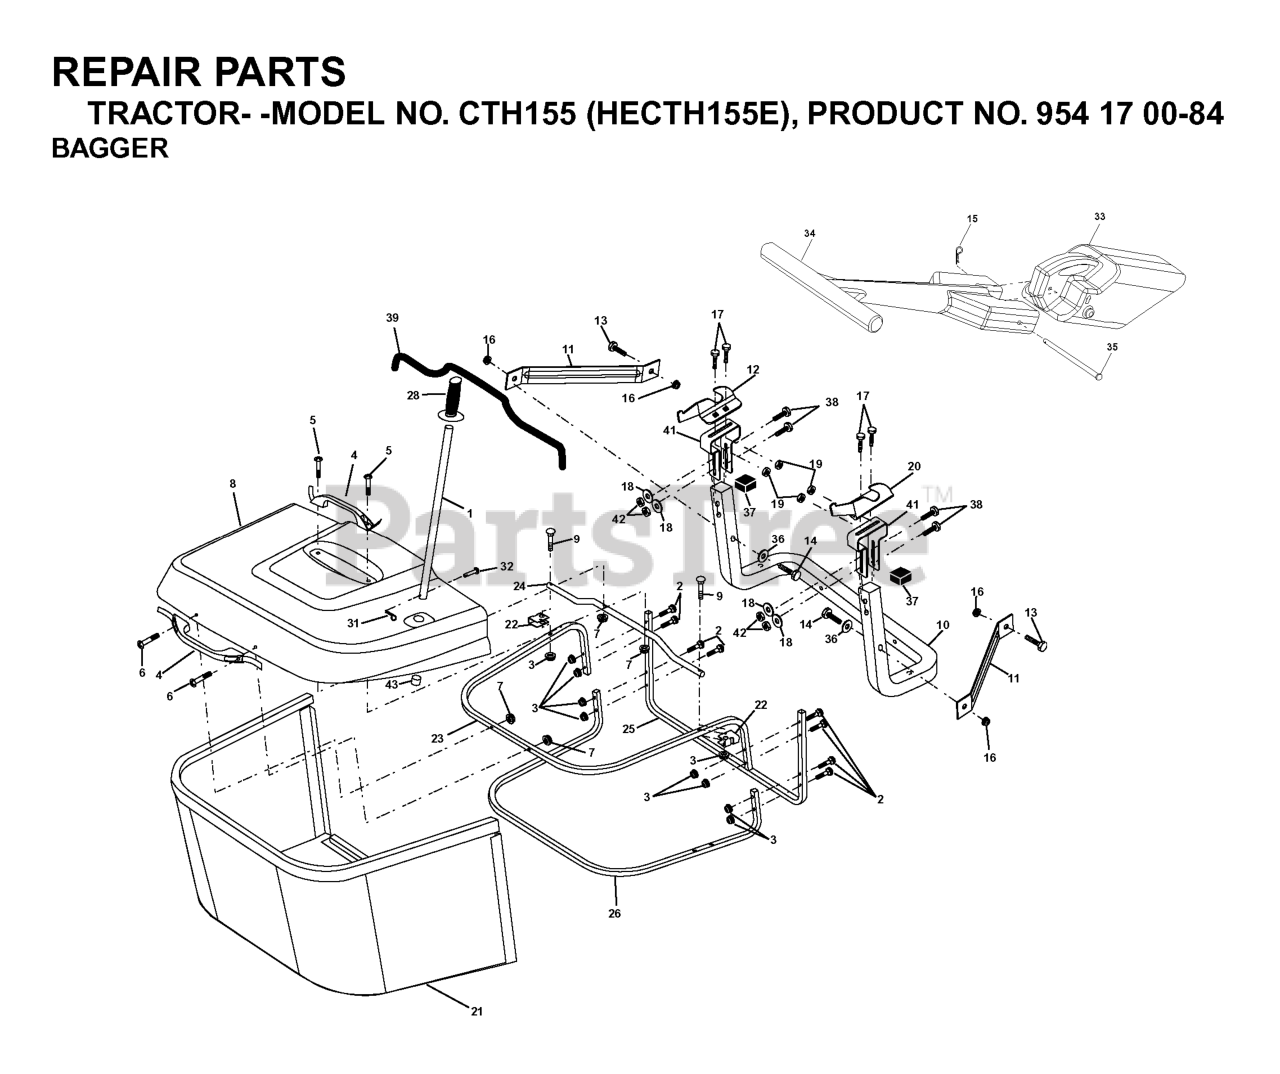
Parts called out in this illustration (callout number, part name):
1	TUBE HANDLE
2	Bolt Carriage 1/4-20 x 2.0 Gr.5
3	NUT T
4	HANDLE.BAGGER.W/LVRS.BLK.CRD
5	SCREW.PAN.HEAD
6	REPL BY 532 75 00-29
8	COVER.PNT.BGR.CRD.WSLOTS.MS668
9	Bolt Carriage 1/4-20 x 2.25d x Gr.5
10	TUBE
11	BRACKET.SUPPORT.UPPER.BAG.CRD
14	BOLT-HEX EAK
15	RETAINER-SPRNG RB
16	NUT LOCK FLG 3/8-16 UNC
17	RP BOLT 5/16-18 X3/4 ZN/YEL GR
18	WASHER M
19	NUT LOCK HEX FLANGE 5/16-18
20	BRACKET
21	GRASS BAG
22	BRKT.SIDE.BAG.CRD
23	TUBE.UPPER.BAG.CRD
24	TUBE.PIVOT.BAG.CRD.BLACK
26	TUBE.LOWER.BAG.CRD
28	GRIP.HANDLE.BLACK
31	RETAINER M
32	RIVET,DRILLED
33	PLUG.MULCHER.92 CRD
34	HANDLE.MULCHER.92.CRD (2 2)
36	WASHER
37	Plug Support Bagger CRD
38	BOLT.5/16-18X2.5
39	SEAL.TRIM.37'
41	BRKT.VERT.ADJ.BAGGER.CRD
42	NUT.71038.31-18.HEX.NYLOCK
43	PLUG, TUBING END
